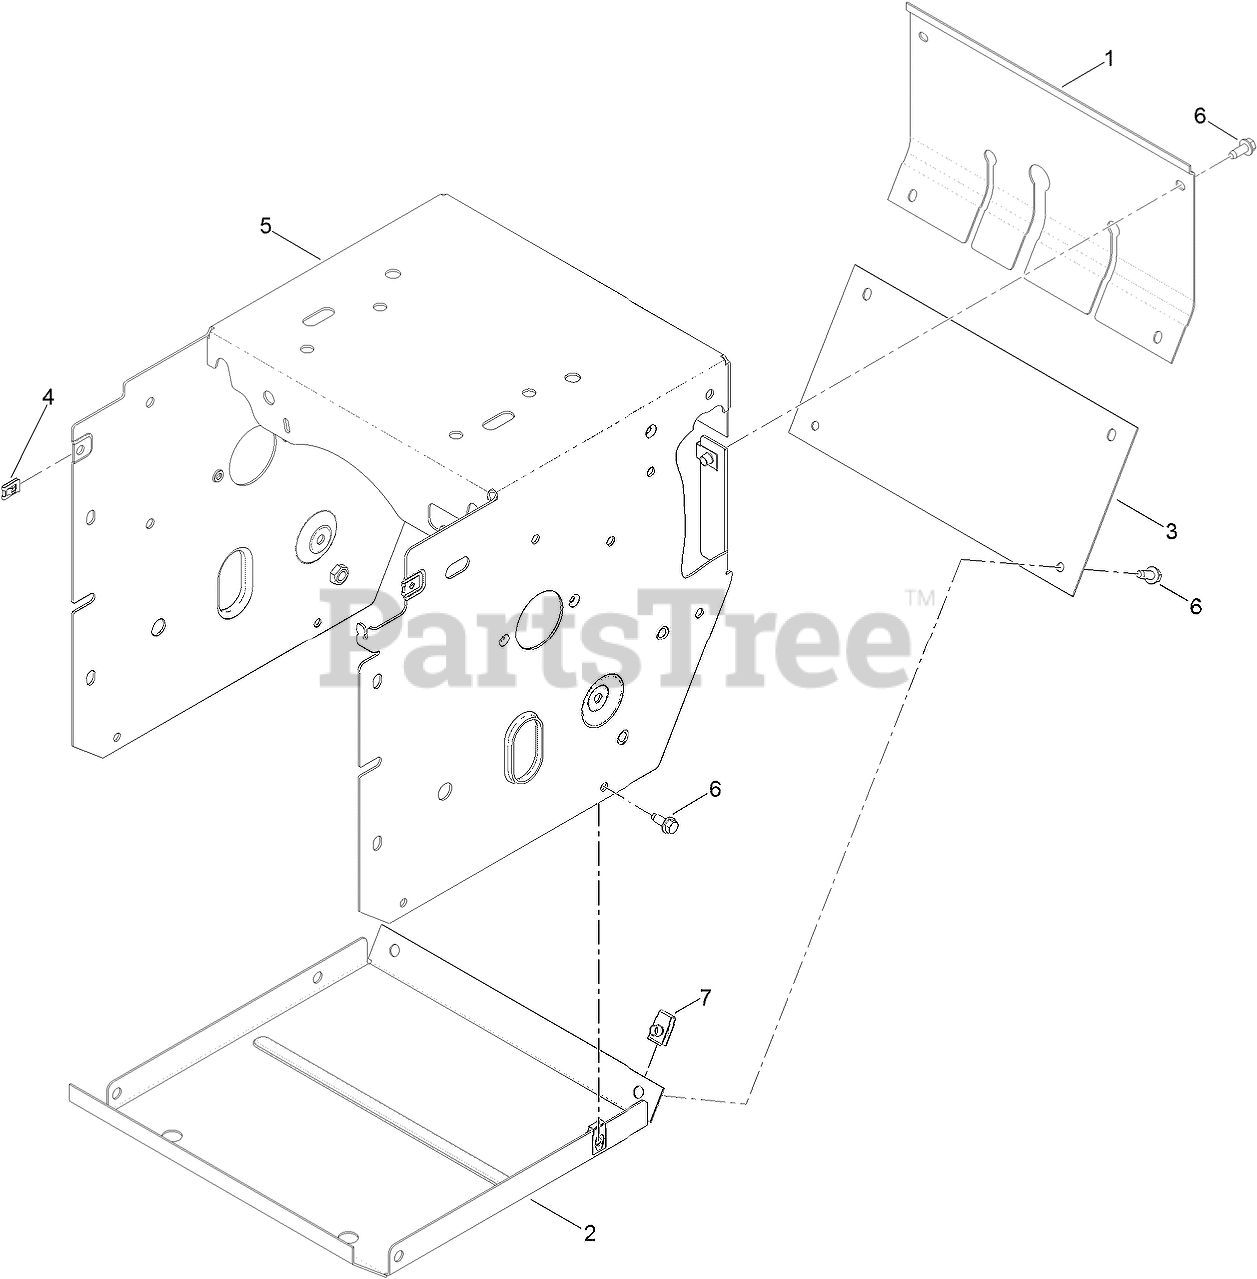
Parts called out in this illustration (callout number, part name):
1	COVER-UPPER
2	PAN-BOTTOM
3	COVER-LOWER
4	NUT-SPEED, U-TYPE
5	FRAME-TRACTION
6	SCREW-HWH
